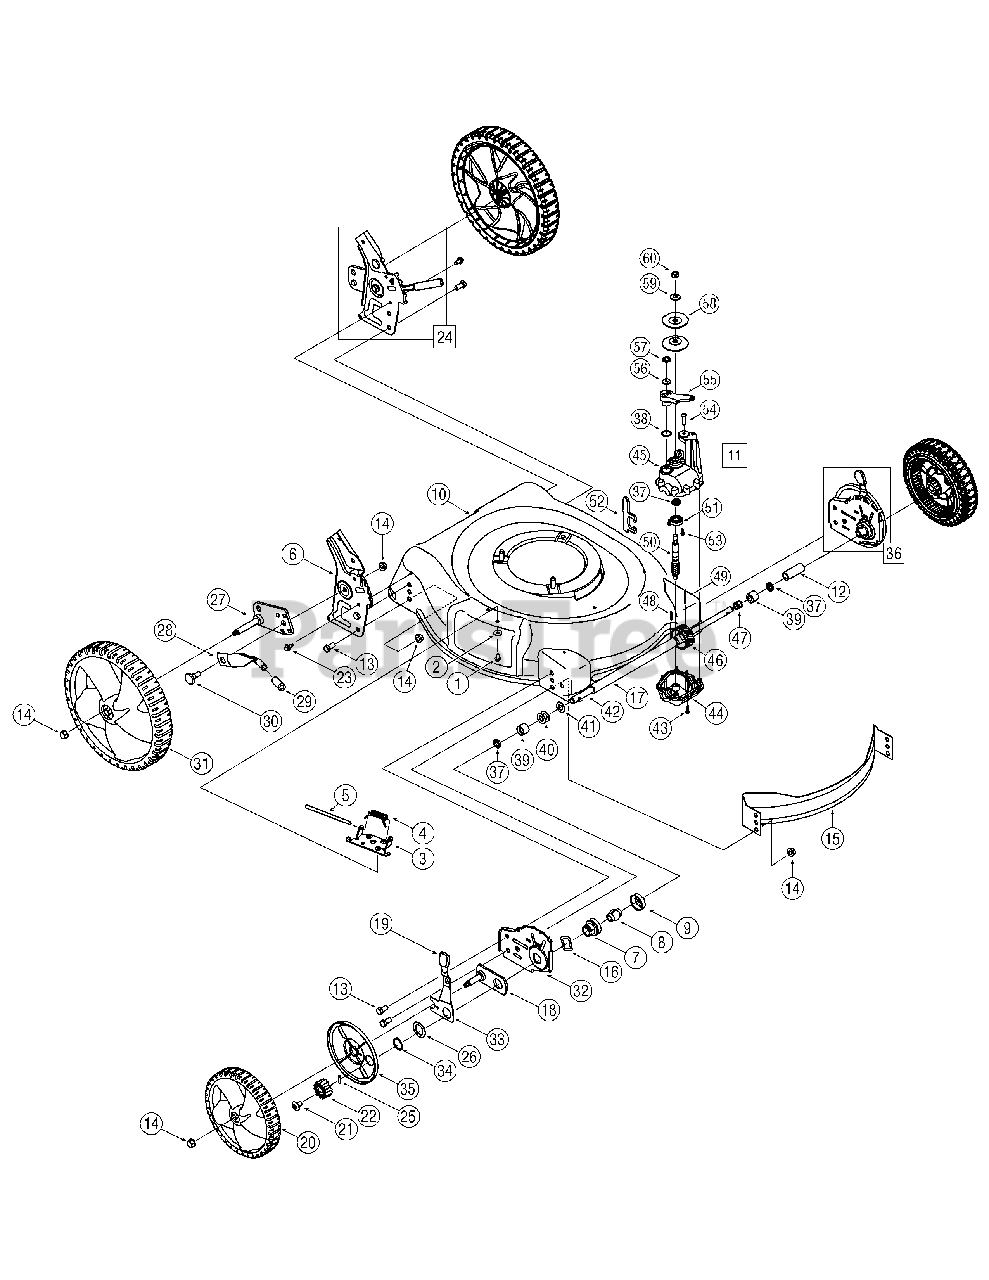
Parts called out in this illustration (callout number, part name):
1	TT Screw 1/4-20 x 0.5
2	Bell Washer.265 x 0.75
3	Deflector Chute Adapter
4	Torsion Spring
5	Hinge Pin
6	Handle Bracket - RH
6	Handle Bracket - LH
7	Bearing Support
8	Bearing Sleeve
9	Bearing Retainer
12	Slev. Spacer 1.4" Lg.
13	Hex Screw, 3/8-16 x.75
14	Flange Lock Nut, 3/8-16
15	Front Baffle
16	Wave Washer
17	Sleeve Spacer 8.985" Lg.
18	Pivot Plate Assembly
19	Adjustment Knob
20	Front Wheel 8 x 1.8
21	Screw, 1/4-20 x .390
22	Gear 14T RH FWD
22	Gear 14T LH FWD
23	TT Scr. w/Washer 1/4-20 x.625
24	Handle Bracket Assembly - LH
24	Handle Bracket Assembly - RH
25	Dowel Pin
26	Washer
27	Pivot Arm Assembly - RH
27	Pivot Arm Assembly - LH
28	Rear Spring Lever
29	Foam Grip
30	Shoulder Scr.500 Dia. x.434
31	Rear Wheel, 12 x 1.8
32	Height Adjuster Plate - RH
32	Height Adjuster Plate - LH
33	Front Lever - RH
33	Front Lever - LH
34	Snap Ring
35	Wheel Dust Cap
36	Height Adjustment Assembly - RH
36	Height Adjustment Assembly - LH
37	Oil Seal
38	O-ring
39	Plastic Bushing
40	Flat Washer
41	Flat Washer
42	Output Shaft
43	Torx Screw
44	Lower Housing
45	Upper Housing
46	28 Tooth Gear
47	Compression Spring
48	Spirol Pin
49	Dowel Pin
50	Pinion Shaft
51	Ball Bearing
52	Shifter Fork
53	Hex Screw
54	Screw, #12-16 x 1.00
55	Clutch Lever
56	Slotted Washer
57	Push Nut
58	Pulley, 3.82 x.313 x.68
59	Bell Washer.325 x.930 x.45
60	Hex Lock Nut, 3/8-24
